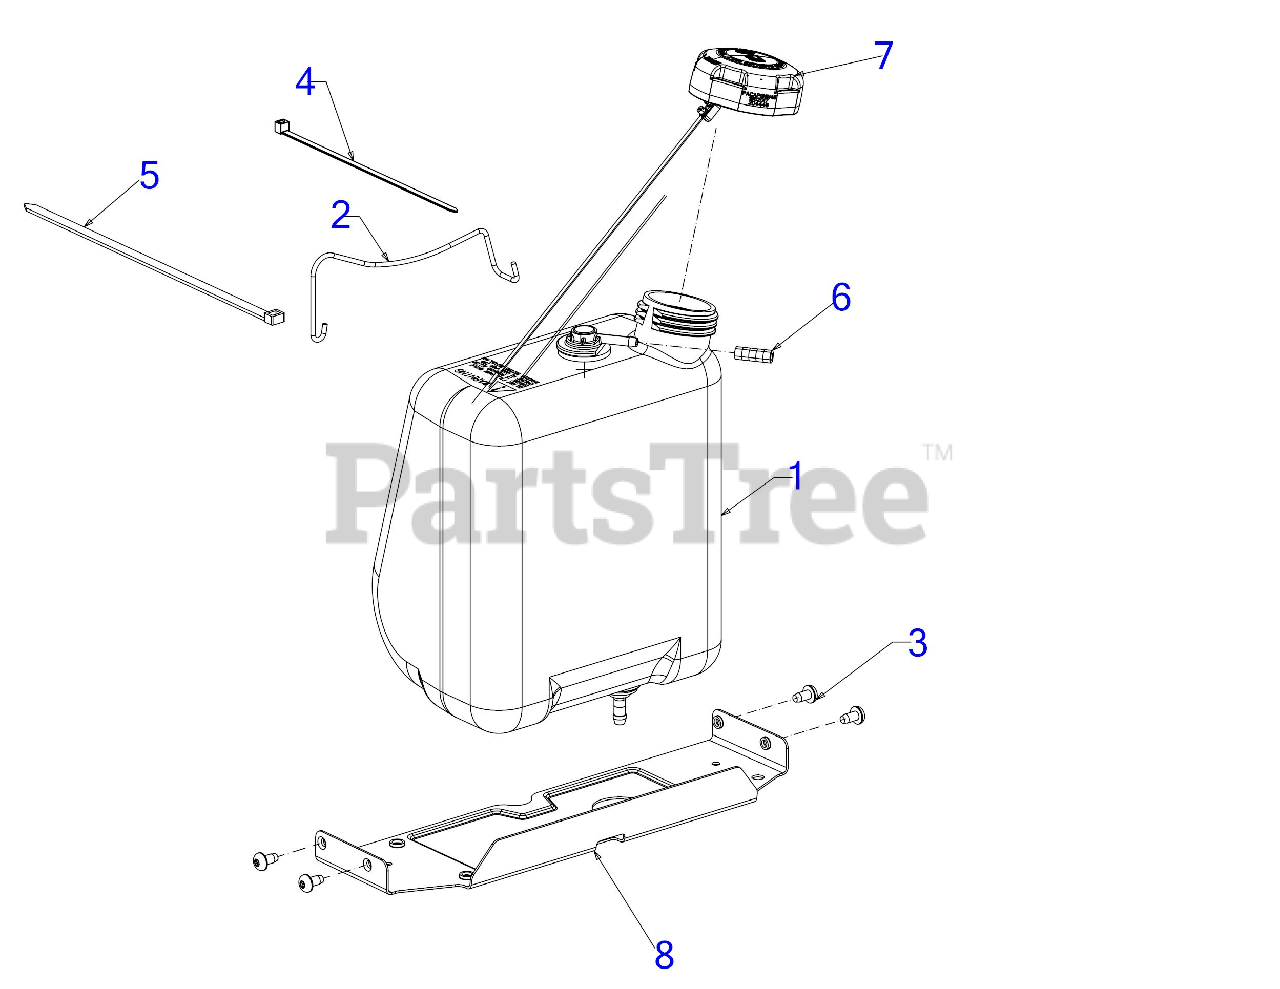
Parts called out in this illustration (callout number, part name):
1	FUEL TANK ASSEMBLY
2	BATTERY ROD ASSEMBLY
3	SCREW 1/4-20 x .5
4	7" CABLE TIE
5	CABLE TIE 36"
6	VENT HOSE 3/16 ID
7	FUEL CAP W/TETHER
8	FUEL TANK BRACKET
